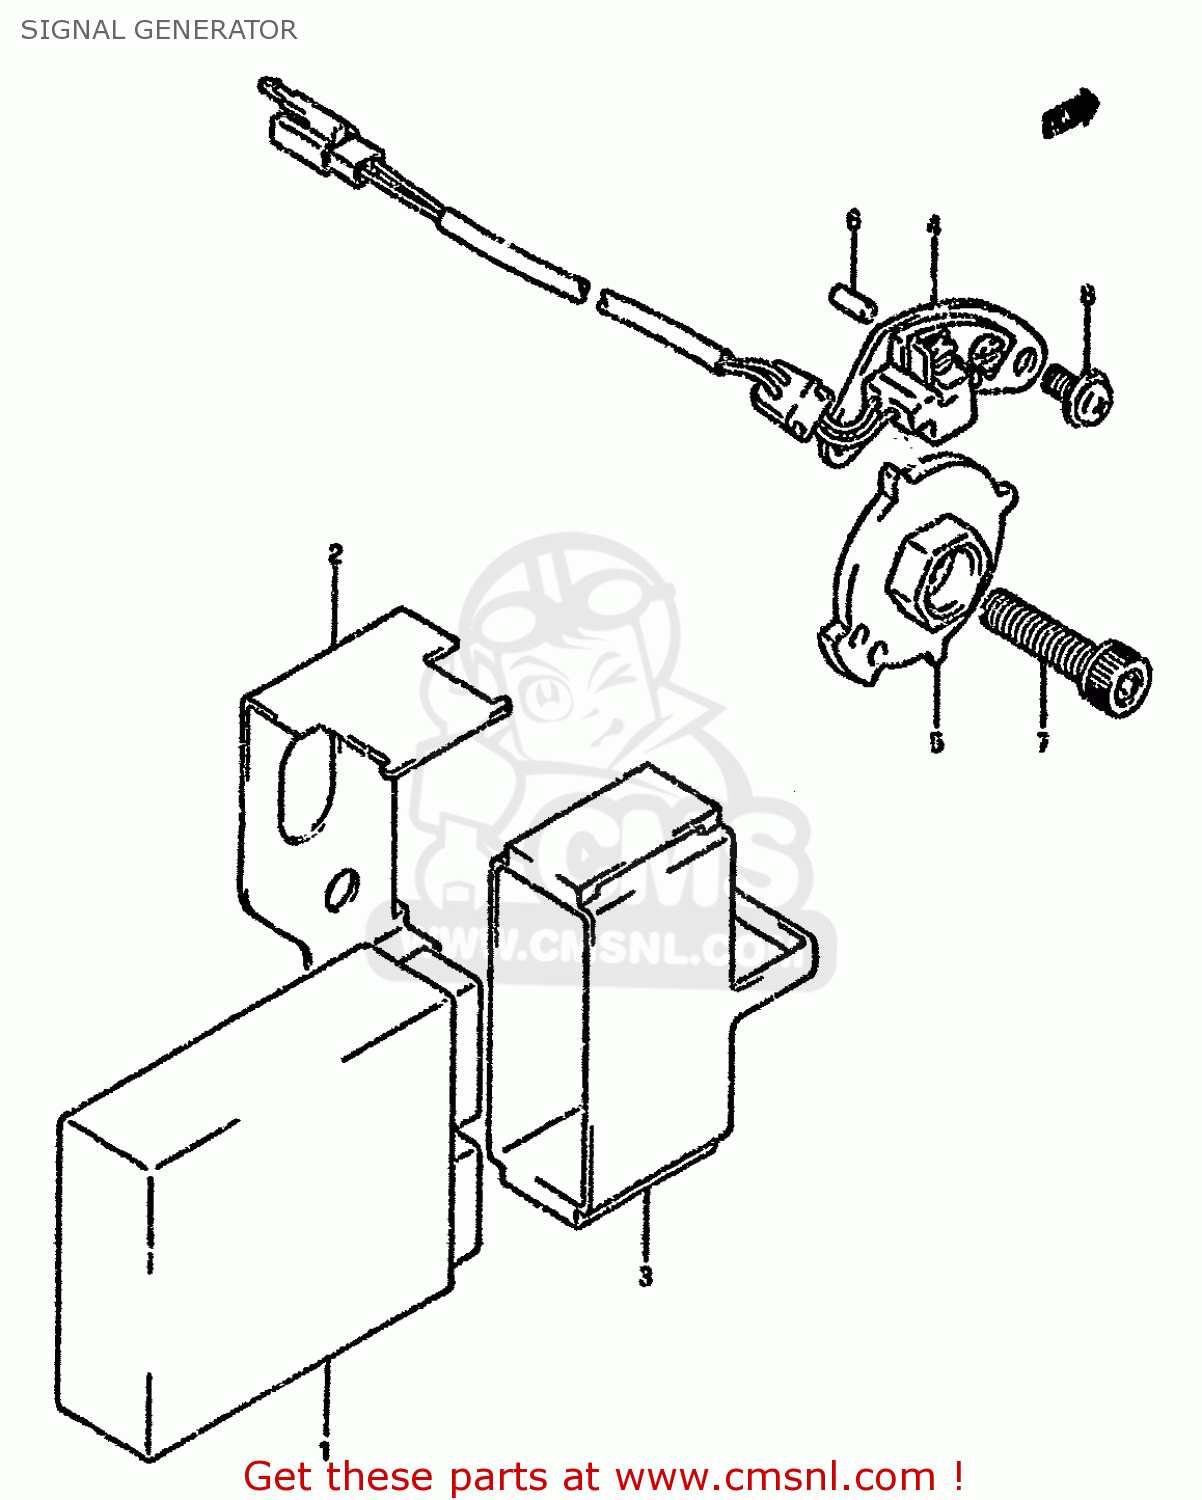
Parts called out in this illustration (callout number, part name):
1	IGNITER ASSY
2	BRACKET,IGNITOR
3	CUSHION,IGNITER
4	STARTER,SIGNAL GENERATOR
5	ROTOR,SIGNAL GENERATOR
6	PIN
7	BOLT
8	SCREW
